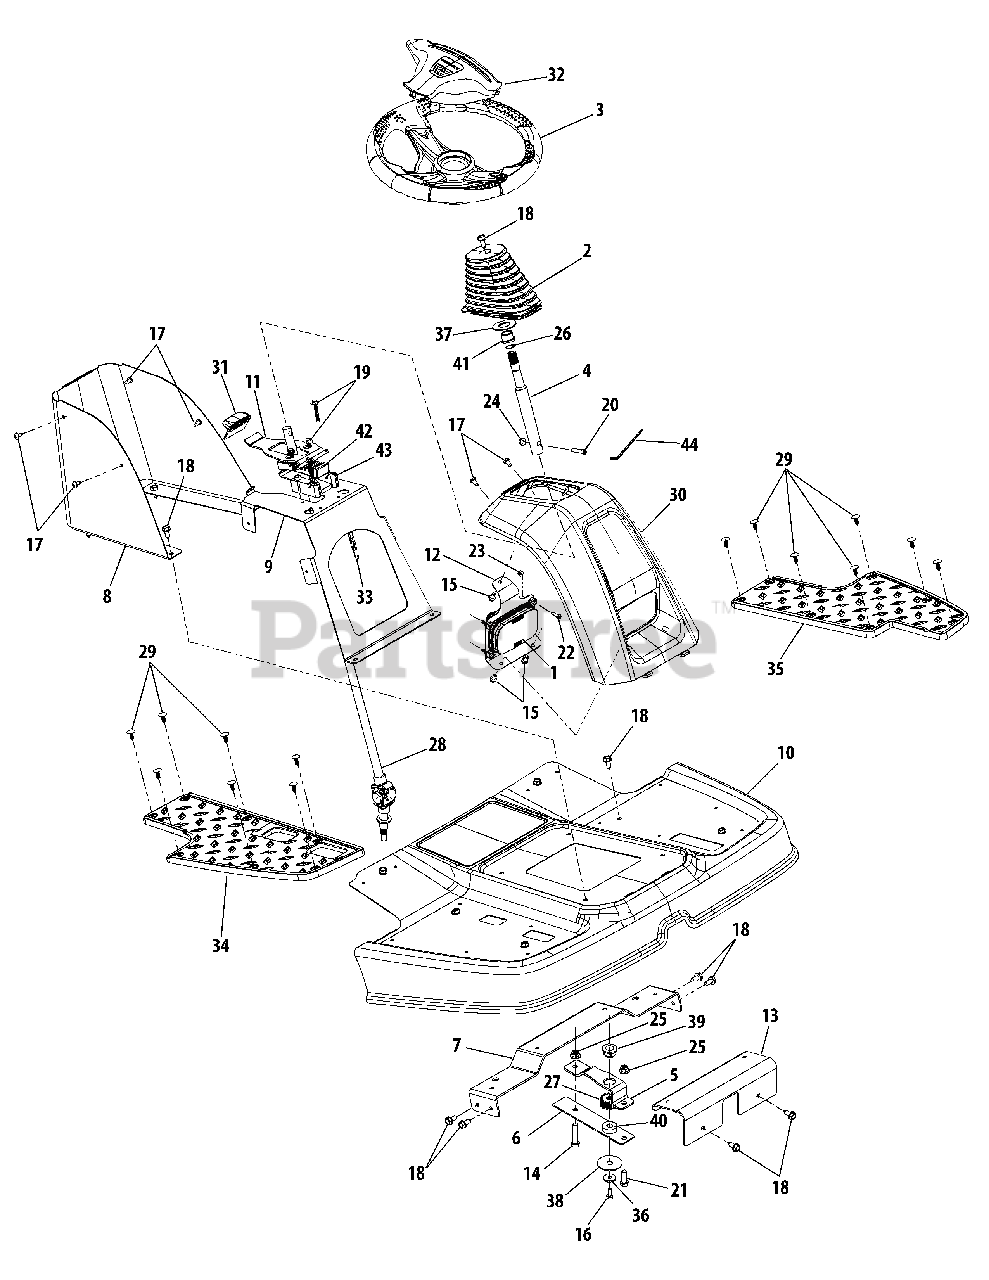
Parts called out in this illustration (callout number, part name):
1	Headlight Assembly
1	Lamp Assembly
2	Boot, Tilt Steering
3	Wheel Assembly, Steering
4	Shaft, Steering
15	Screw, Hex Wash. Hd. Lock, 1/4-15 x .5
16	Screw, Hex Cap, 1/4-20 x .625 Gr5 Lock
17	Screw, Pan Hd. Torx, 1/4-20 x .5
18	Screw, Hex Wash. Hd. Tapp, 5/16-18 x .75
19	Screw, Hex Wash Hd. Tapp, 1/4-20 x 1.625
20	Screw, Socket Hd. 1/4-20 x 1.25
21	Screw, Hex Cap, 3/8-16 x 1.0 Gr5
22	Screw, Pan Phillips Hd Tapp, #10-24 x .75
23	Nut, Hex Insert Lock, #10-24 Gr2
24	Nut, Hex Insert Flange Lock, 1/4-20 GrF
25	Nut, Hex Insert Flange Lock, 3/8-16 GrF
26	Ring, Retaining, .56 Dia.
27	Gear, Steering, 14T
28	Shaft, Steering
29	Clip, Ratchet, .25
30	Housing, Pedestal
31	Lever, Tilt
32	Cover, Steering Wheel;
33	Spring, Extension, .38 x 5.6
34	Pad, Foot, RH
35	Pad, Foot, LH
36	Washer, Flat, .265 x .938 x.12
37	Washer, Flat, .885 x 1.85 x .06
38	Washer, Thrust, .445 x 1.92 x .06
39	Bearing, Hex Flange
40	Bearing, Flange, 7/16
41	Bearing, Flange, .63 x .62
42	Index, Tilt Steering
43	Block, Tilt Steering
44	Wrench, Allen, 3/16
